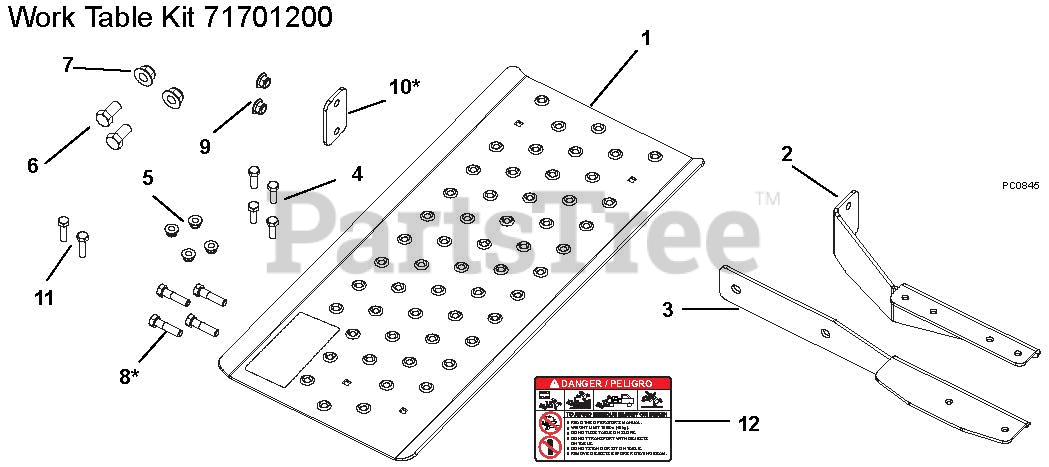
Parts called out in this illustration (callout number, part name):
1	BRKT, LOG SPLITTER WORK TABLE
2	BRKT, REAR TABLE MOUNT
3	BRKT, FRONT TABLE MOUNT
4	@BLT-RHDSSQNK .31-18X1.00 G5YZ
5	@NUT-LK-NYL-FLG .31-18 YWZC
6	@BLT-HEX .50-13X1.00 GR5 YWZC
7	@NUT-LK-TOP-FLG .50-13 YWZC
8	@BLT-HEX .38-16X1.50 GR5 YWZC
9	@NUT-LK-TOP-FLG .38-16 YWZC
10	PLATE, WORK TABLE SPACER
11	@BLT-HEX .38-16X1.25 GR5 YWZC
12	DECAL,WORK TABLE
